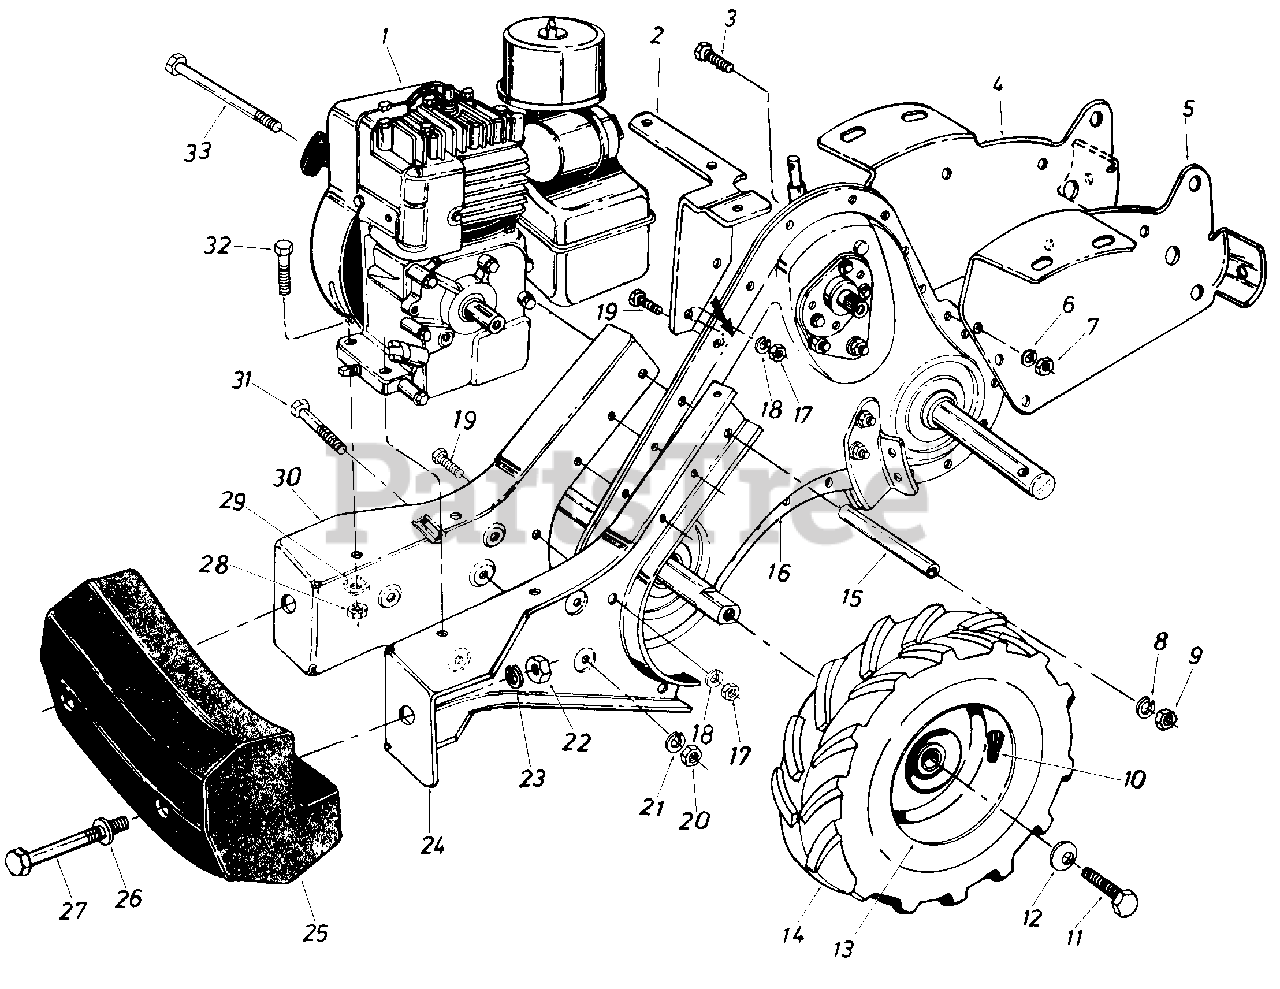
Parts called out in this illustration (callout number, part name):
1	Engine
2	Belt Cover Mounting Brkt.
3	Hex Bolt 3/8-16 x 1.00" Lg.
7	Hex Nut 3/8-16 Thd.
8	L-Wash. 5/16" I.D.
9	Hex Nut 5/16-18" Thd.
10	Air Valve
11	Hex Bolt 5/16-24 x .62" Lg.
12	Bell-Wash. .345" I.D. x .88"
13	Wheel Rim Ass'y. Only
14	L.H. Wheel Ass'y. Comp.
15	Spacer 3/8" I.D. x 3.38" Lg.
16	Transmission Comp.
17	Hex Nut 5/16-18 Thd.
18	L-Wash. 5/16" I.D.
19	Hex Bolt 5/16-18 x .75" Lg.
20	Hex Nut 3/8-16 Thd.*
21	L-Wash. 3/8" I.D.-H.D.
22	Hex Nut 1/2-13 Thd.
23	L-Wash. 1/2" I.D.
26	Fl-Wash. .510" I.D. x 1.0"
27	Hex Bolt 1/2-13 x 5.00" Lg.
28	Hex Nut 5/16-18 Thd.*
29	L-Wash. 5/16" I.D.
32	Hex Bolt 5/16-18 x 1.50"
33	Hex Bolt 5/16-18 x 4.75" Lg.-Gr. 2
